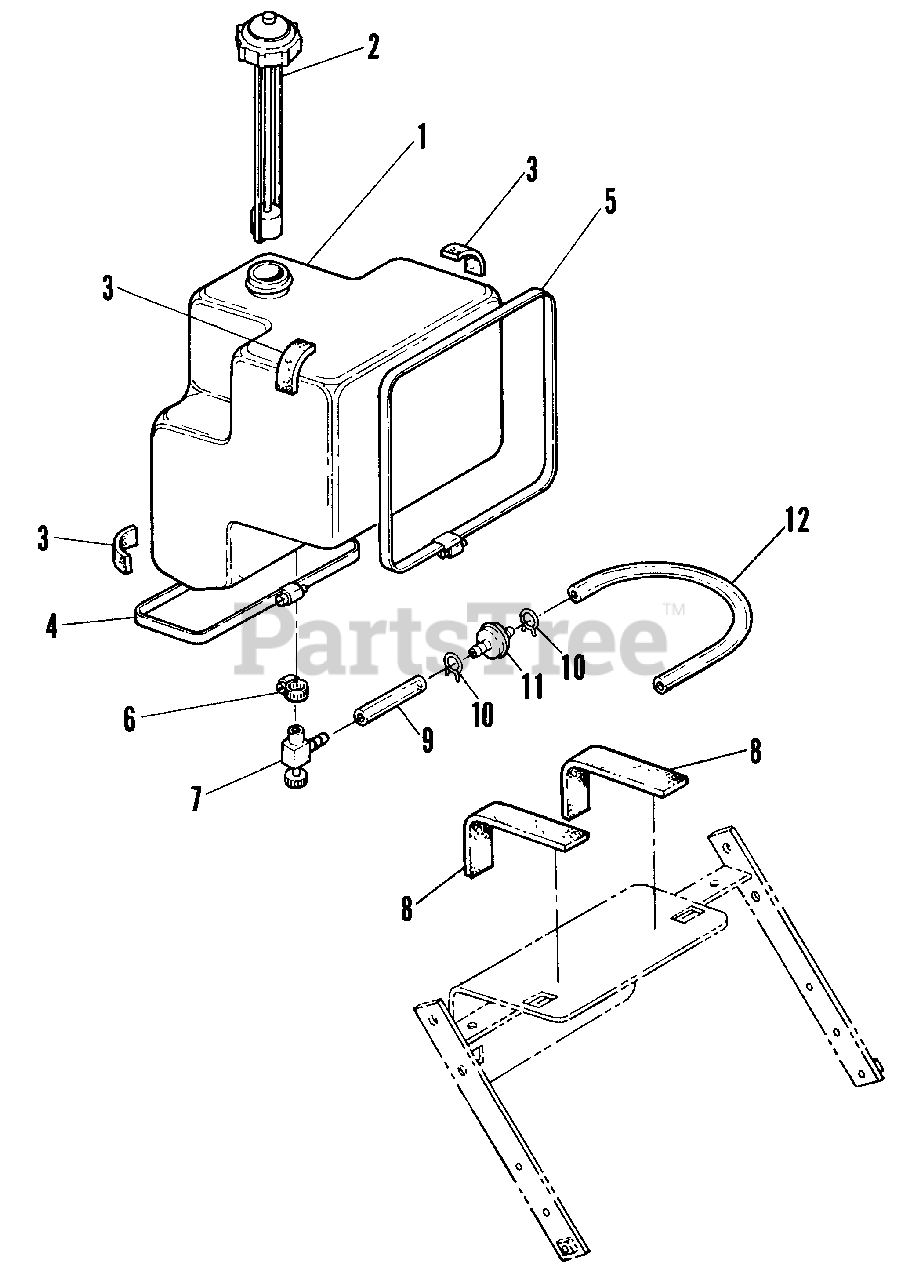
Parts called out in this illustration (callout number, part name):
1	TANK, Fuel w/Valve & Clamp
2	CAP, Fuel Wt Gauge
3	PAD, Fuel Tank
4	BAND, Fuel Tank (Short)
5	BAND, Fuel Tank (Long)
6	CLAMP, Fuel Tank Valve
7	VALVE, Fuel Shut-Off
8	PAD, Fuel Tank Saddle
9	LINE, Fuel 3 1/2
10	SPRING CLAMP, Gas Hose
11	FILTER, Fuel
12	LINE, Fuel 16
